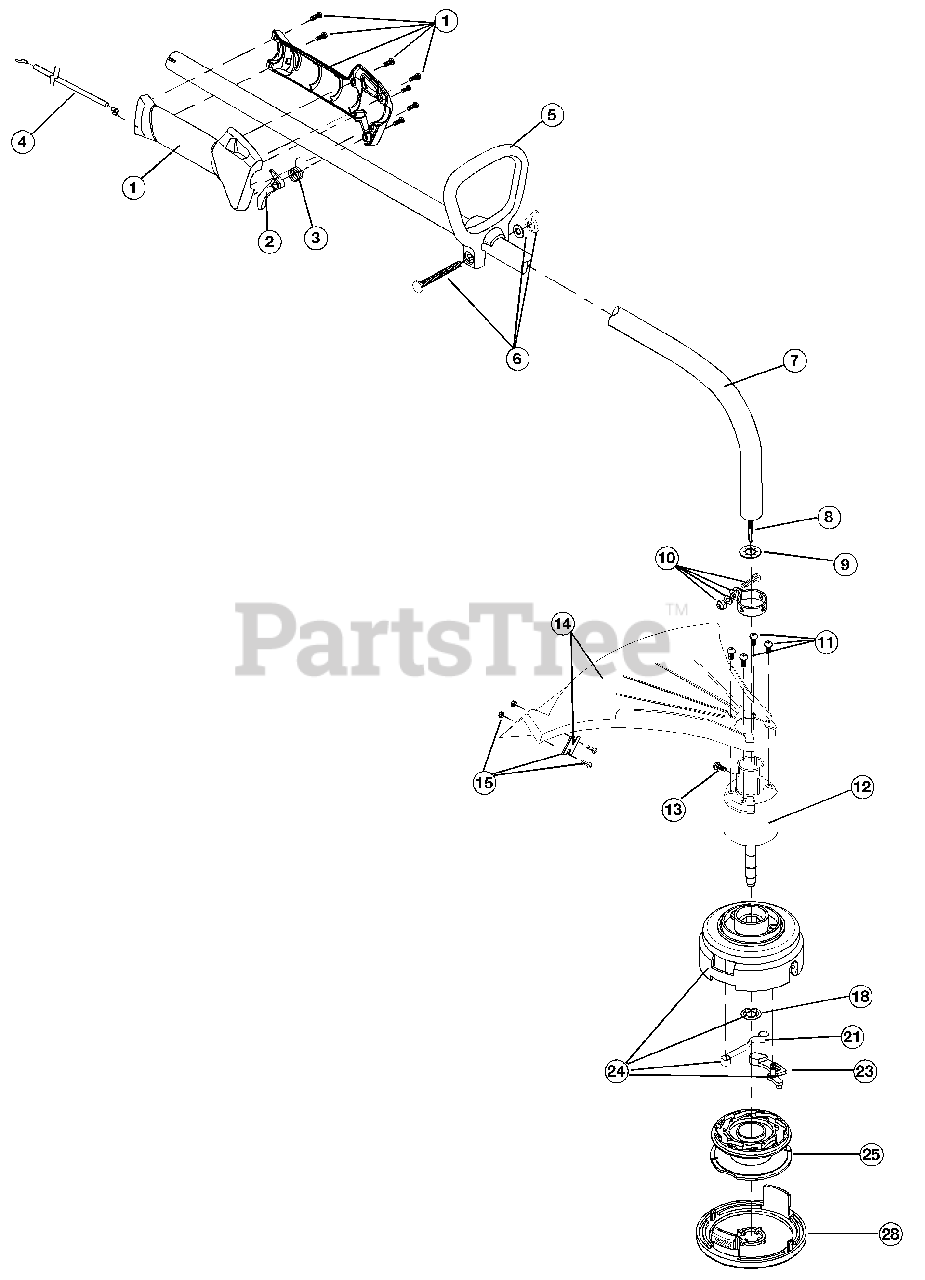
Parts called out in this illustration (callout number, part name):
1	Throttle Housing and Trigger Assembly (includes 2 & 3)
2	Throttle Trigger Spring
3	Throttle Trigger
4	Throttle Cable Assembly
5	D-Handle Assembly (includes 6)
6	D-Handle Hardware
7	Drive Shaft Housing Assembly
8	Flexible Drive Shaft
9	Palnut
10	Lower Clamp Assembly
11	Shield Mounting Screw
12	Bushing Housing Assembly w/shaft (For ALF Head)
13	Anti-Rotation Screw
14	Shield and Blade Assembly (includes 15)
15	Blade Assembly
18	Retainer
21	Pawl Spring
23	Ratchet Pawl
24	Outer Spool w/ Retainer (includes 18, 21, 23)
25	Inner Reel
28	Spool Cover
